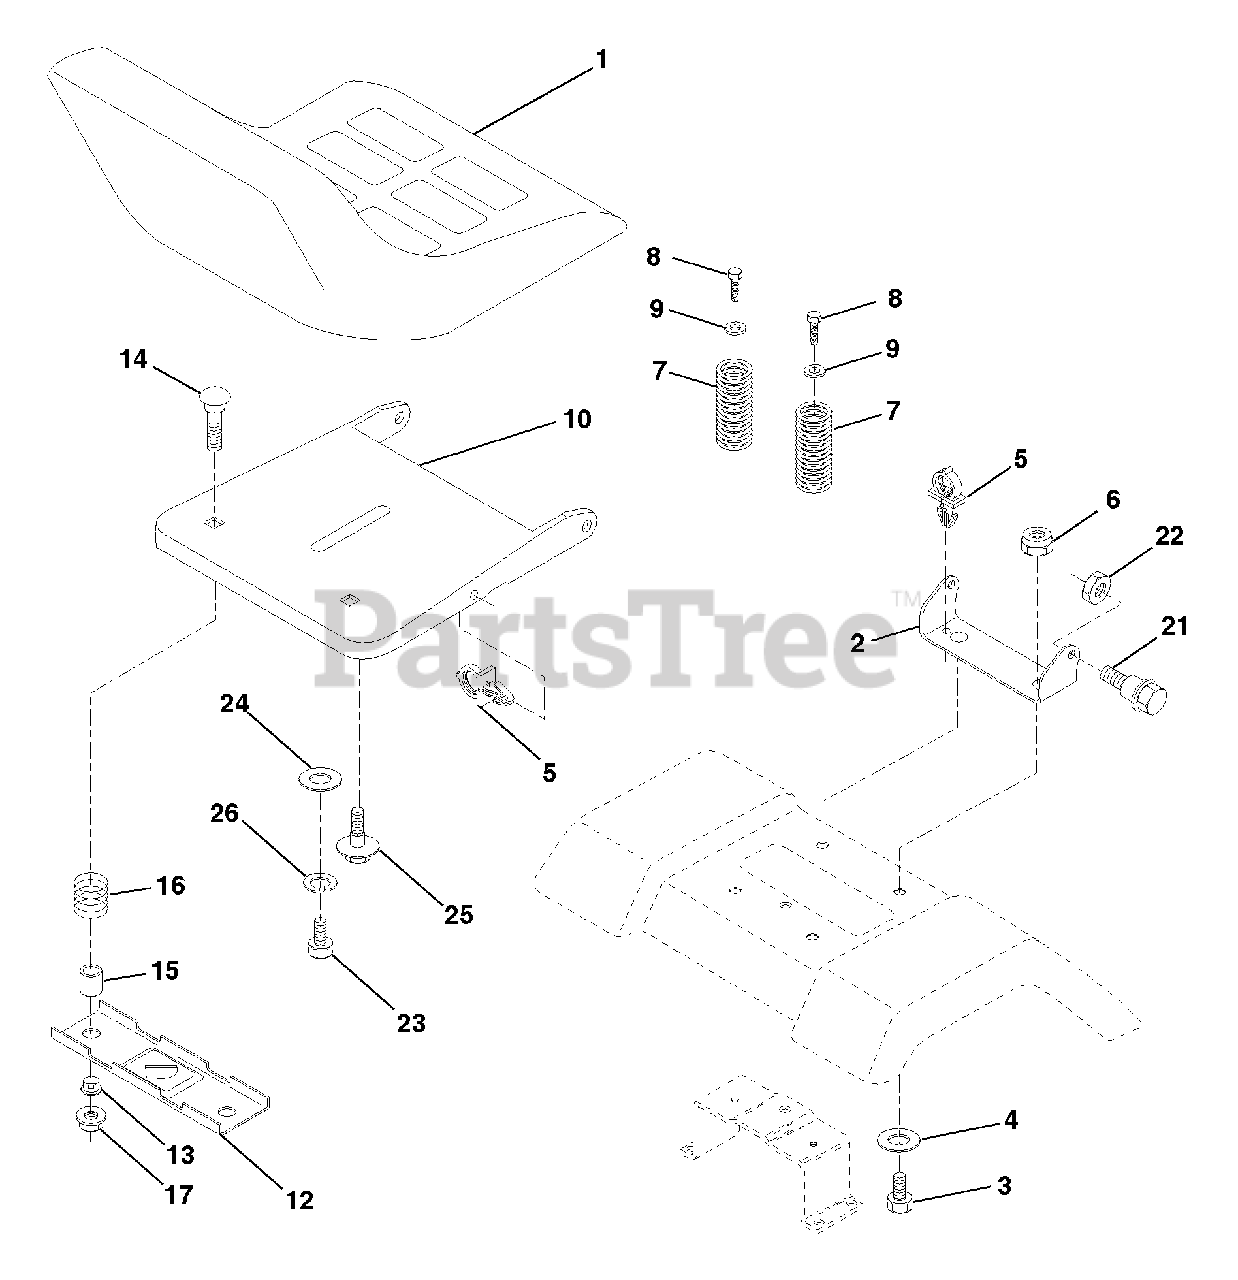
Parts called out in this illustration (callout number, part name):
1	Seat
2	Bracket Pivot Seat 8 720
3	Bolt Fin Hex 3/8-16unc X 1
4	Washer 13/32 X 1 X 10 Ga
5	Clip Push-In
6	Nut Hex w/Ins. 3/8-16 Unc
7	Spring Seat Cprsn 2 250 Blk Zi
8	Screw Thdrol 3/8-16 X 1 Ty-tt
9	Washer 13/32 X 1 X 14 Ga.
10	Pan Seat
12	Bracket Mounting Switch
13	Bushing Snap Blk Nyl 50 Id
14	Bolt Rdhd Sqnk 1/4-20 x 1-1/2
15	Spacer Split 28 x 96 Yel Zinc
16	Spring Cprsn 1 27 Blk Pnt
17	Nut Lock 1/4 Lge Flg Gr 5 Zinc
21	Bolt Shoulder 5/16-18 Unc
22	Nut Hex Lock W/Ins 5/16-18
23	Bolt, Hex Head, Fin 1/2-13 x 7/8 Grade 5
24	Washer 17/32 X 1-3/16 X 12 Ga.
25	Bolt Shoulder 5/16-18 X 62
26	Washer Lock
